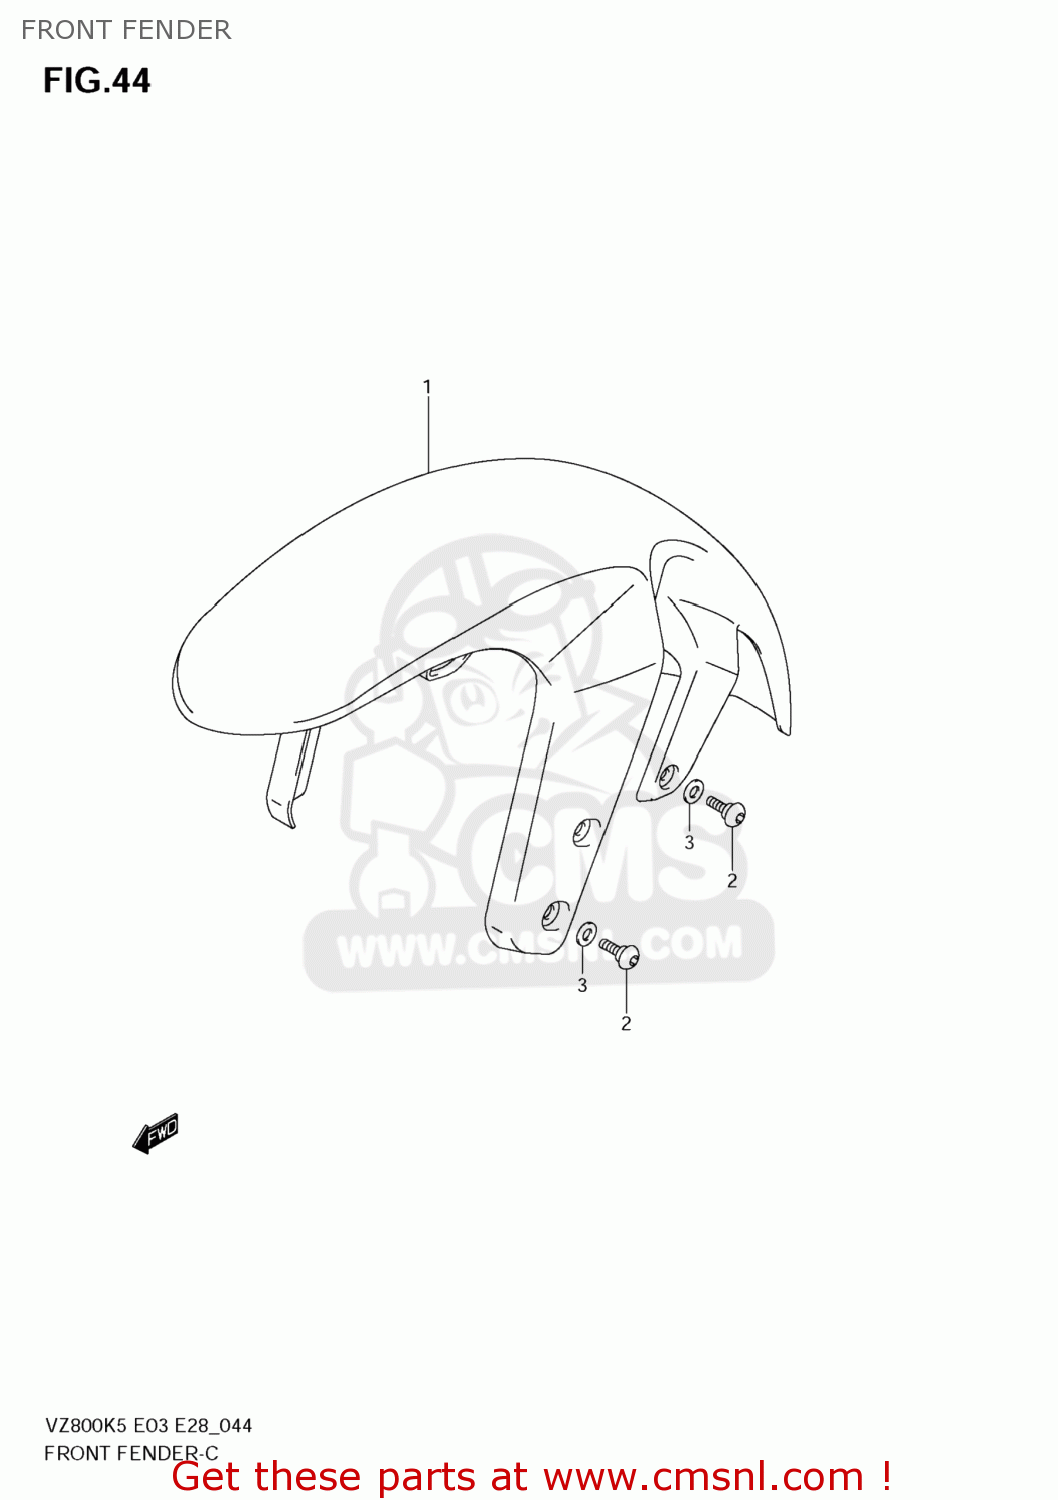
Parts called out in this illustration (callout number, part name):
1	FENDER,FR
2	SCREW(6X16)
3	WASHER,FR FENDER
